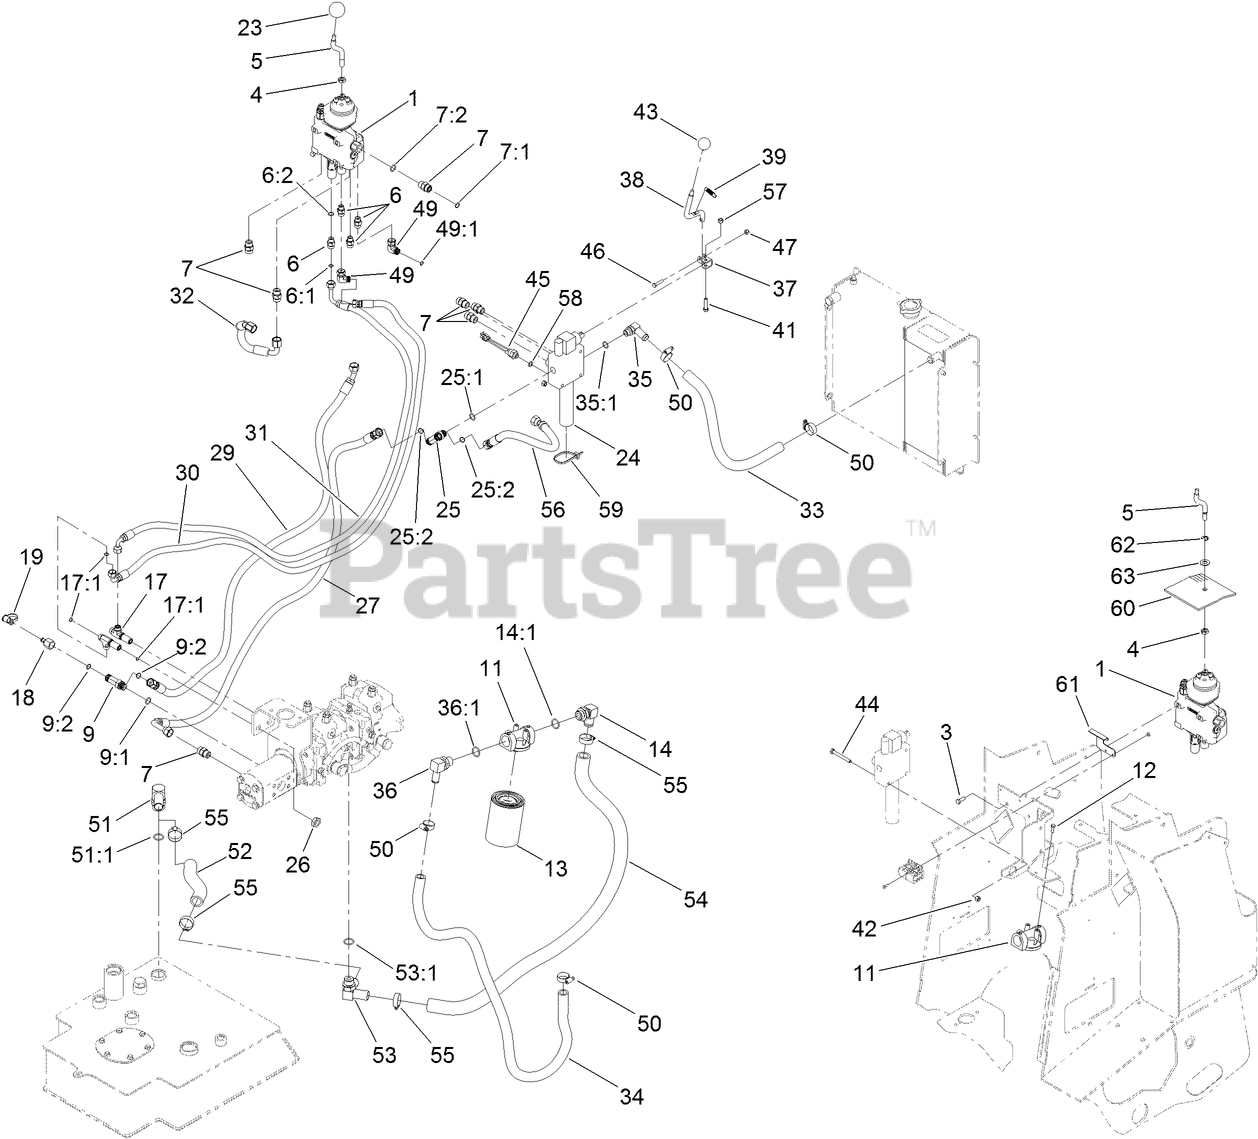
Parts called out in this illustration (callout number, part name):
1	2 SPOOL VALVE ASM
3	SCREW-HH
5	SHAFT-HANDLE, LIFT/TILT
6	FITTING-STRAIGHT
6:1	O-RING
6:2	O-RING
7	FITTING-STRAIGHT
7:1	O-RING
7:2	O-RING
9	FITTING-TEE
9:1	O-RING
9:2	O-RING
11	HEAD-FILTER
12	SCREW-HH
13	FILTER-OIL
14	FITTING-90
14:1	O-RING
17	FITTING-TEE, BULKHEAD
17:1	O-RING
18	FITTING
19	CAP-DUST
24	DOUBLE DETENT VALVE ASM
25	FITTING-HYD, TEE
25:1	O-RING
25:2	O-RING
26	NUT-LOCK
27	HYD HOSE ASM
29	HYD HOSE ASM
30	HYD HOSE ASM
31	HYD HOSE ASM
32	HYD HOSE ASM
33	HOSE-RETURN
34	HOSE-RETURN
35	FITTING-ELBOW, 90
35:1	O-RING
36	FITTING-ELBOW, 90
36:1	O-RING
37	BRACKET-AUXILARY
38	HANDLE ASM
39	SPRING-EXTENSION
41	SCREW-HH
42	NUT-LOCK, NI
44	SCREW-HH
45	SWITCH-BALL
46	BOLT-SHOULDER
47	NUT-LOCK, NI
49	FITTING-HYD, 90 DEG
49:1	O-RING
50	CLAMP-HOSE
51	FITTING-HYD, 90 DEG
51:1	O-RING
52	HOSE-SUCTION
53	CONNECTOR
53:1	O-RING
54	HOSE-RETURN
55	CLAMP-HOSE
56	HYD HOSE ASM
57	NUT-LOCK, NI
58	O-RING
59	TIE-CABLE
60	DEFLECTOR-AIR
61	BRACKET-DEFLECTOR
62	RING-RETAINING
63	WASHER-PIVOT
